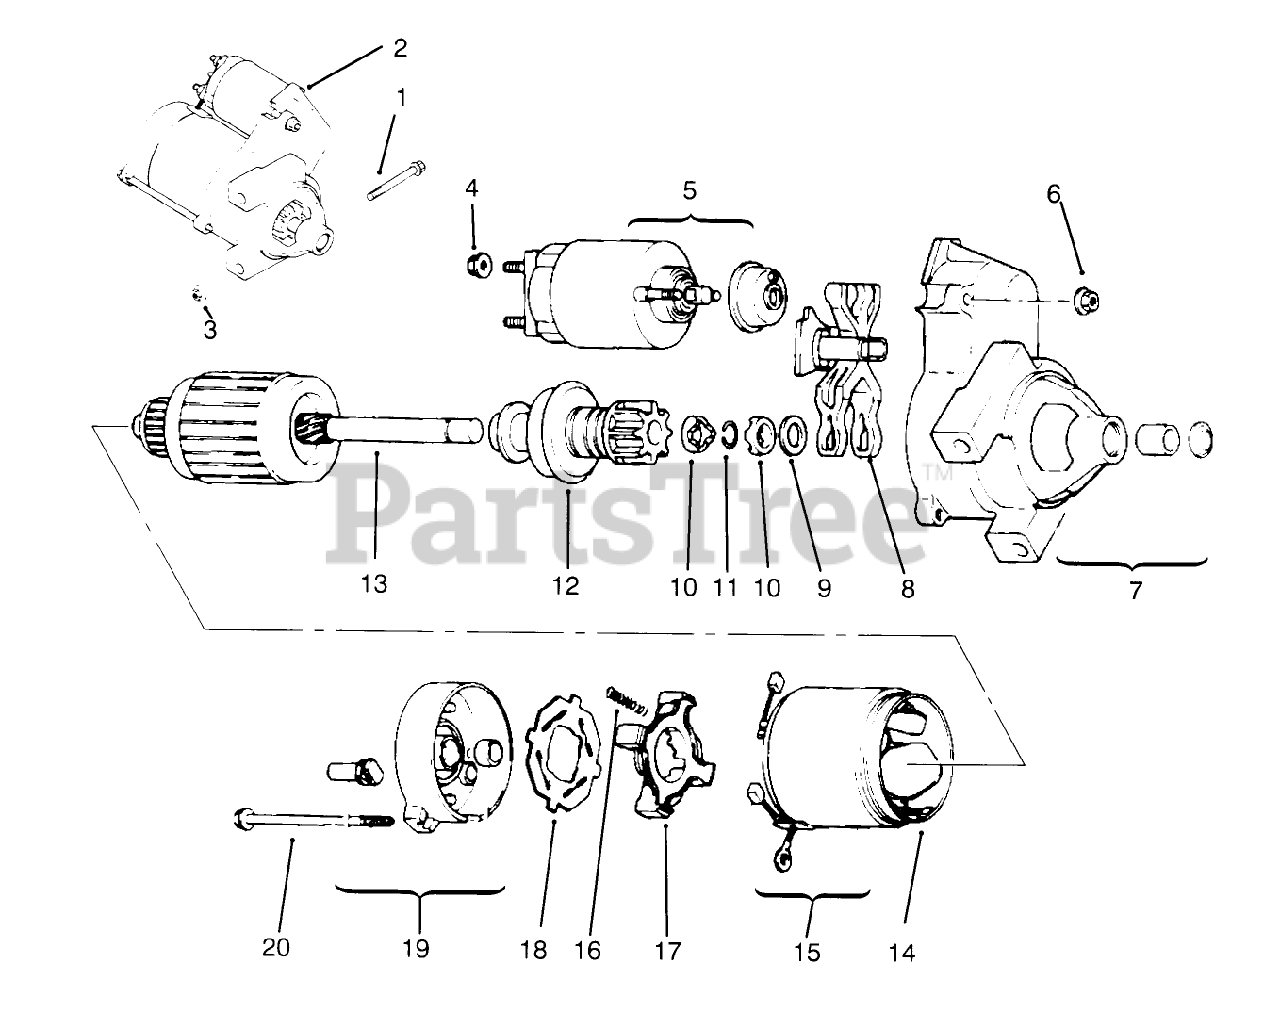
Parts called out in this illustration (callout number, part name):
1	Screw M8x1.25x80 (Only On: 72103, 72083)
2	Starter-Solenoid Shift (Incl. Ref. # 4-20)
4	Nut
5	Solenoid
6	Nut Starter
7	Cap-Drive End
8	Lever Starter Drive
9	Washer-Thrust (Only On: 72103, 72083)
10	Nut-Stop Collar
11	Ring-Retainer
12	Drive-Pinion
13	Armature-Starter
14	Frame
15	Kit-Brush (Incl. Ref. # 16)
16	Spring-Brush
17	Holder-Brush
18	Insulator
19	Cap-Commutator End
20	Bolt
